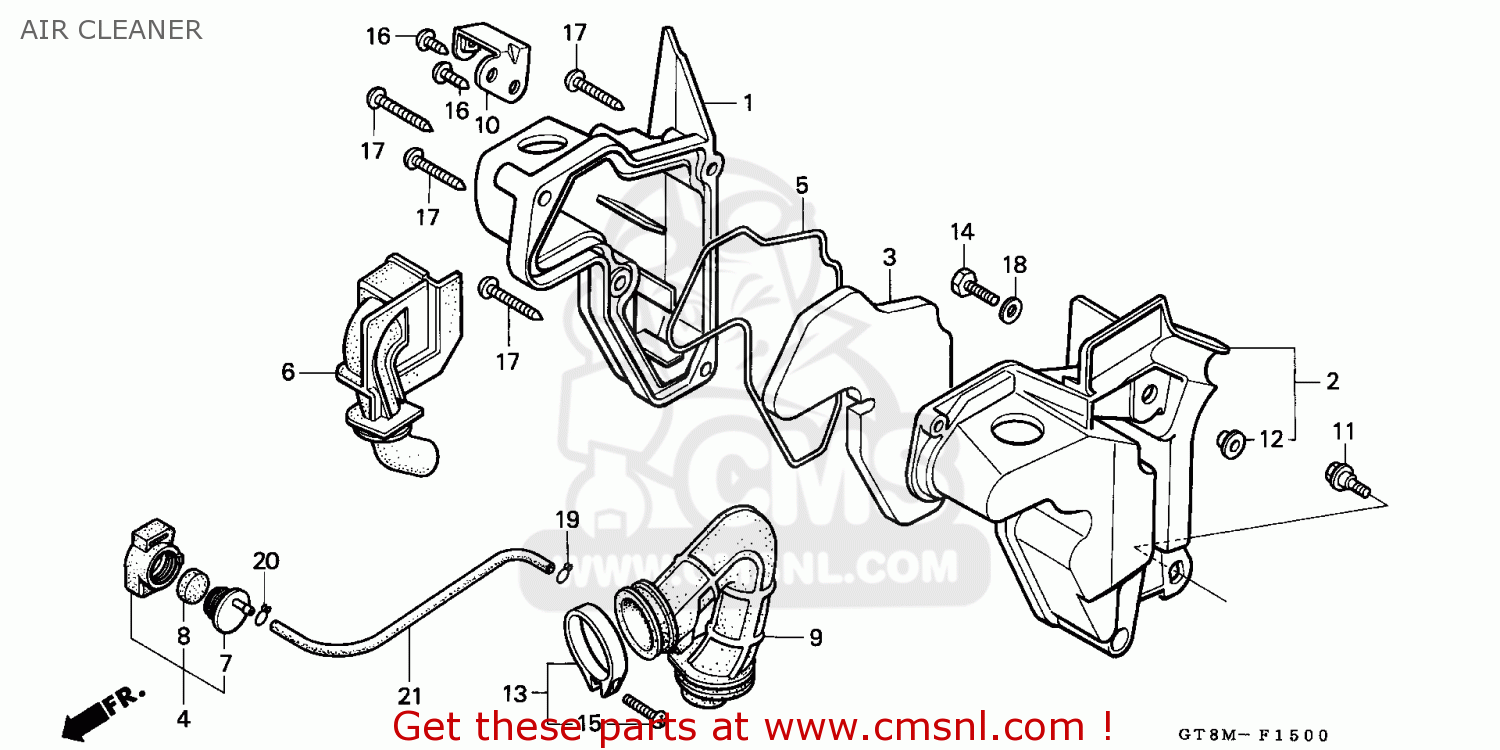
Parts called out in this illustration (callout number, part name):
1	COVER AIR/C CASE
2	CASE,AIR/C
3	ELEMENT AIR/C
4	SUB CLEANER ASSY.
5	SEAL,AIR/C COVER
6	DUCT,AIR/C INLET
7	PLUG,AIR CLEANER
8	ELMT,BYSTART,CHBR
9	TUBE,AIR/C CONN
10	STAY,SPROCKET COV
11	BOLT,FLANGE,6MM
12	WASHER,6X20
13	BAND 34,AIR CLEAN
14	BOLT,HEX.,6X18
15	SCREW,PAN,4X25
16	SCREW,TAPPING
17	SCREW,TAPPIN,5X40
18	WASHER,PLAIN,6MM
19	CLIP B7,TUBE
21	TUBE,3.5X150MM
